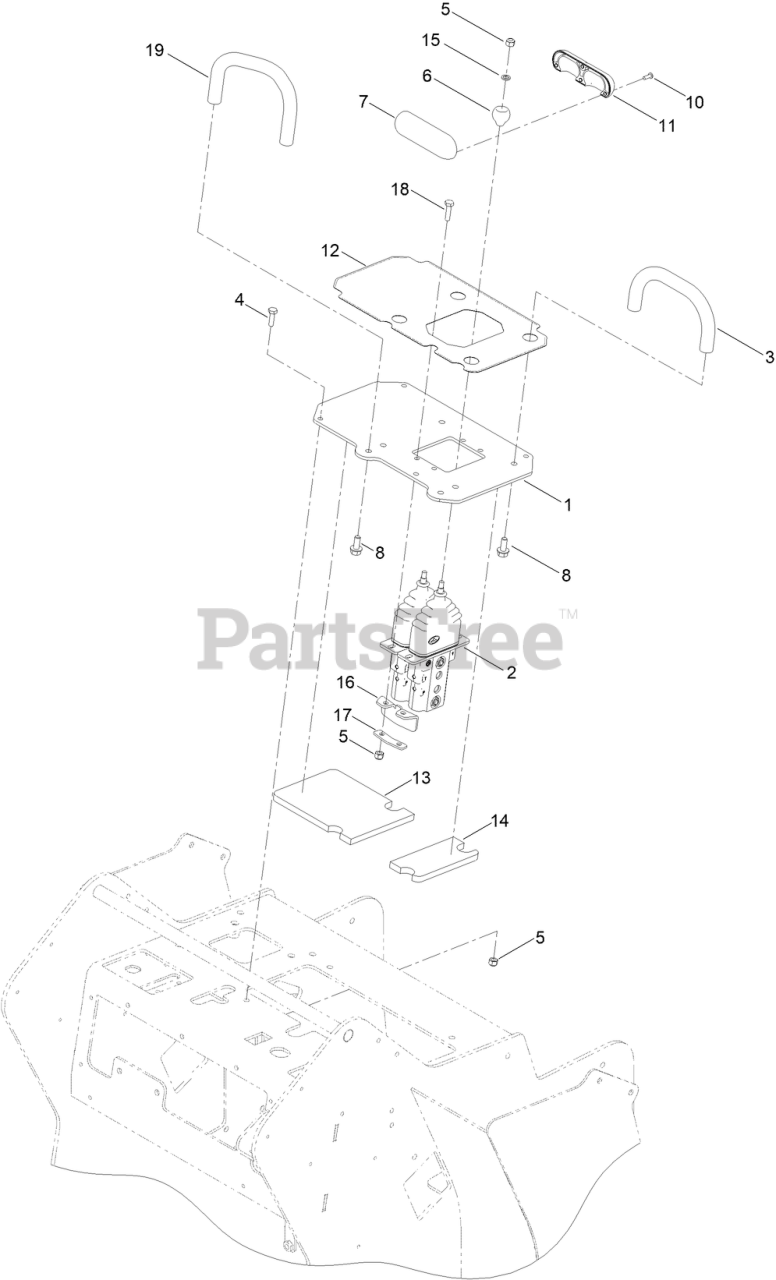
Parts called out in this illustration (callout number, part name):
1	PLATE-CONTROL
2	VALVE-CONTROL
3	BAR-REFERENCE
4	SCREW-HH
5	NUT-LOCK, NI
6	BALL-TRACTION
7	HANDLE-CONTROL
8	SCREW-HHF
10	SCREW
11	HANDLE-TRACTION
12	DECAL-CONTROL PANEL
13	FOAM-SHIELD, HEAT
14	FOAM-SHIELD, HEAT
15	SPACER-BEARING
16	COVER-RUBBER
17	PLATE-CLAMP
18	SCREW-HH
19	BAR-REFERENCE
